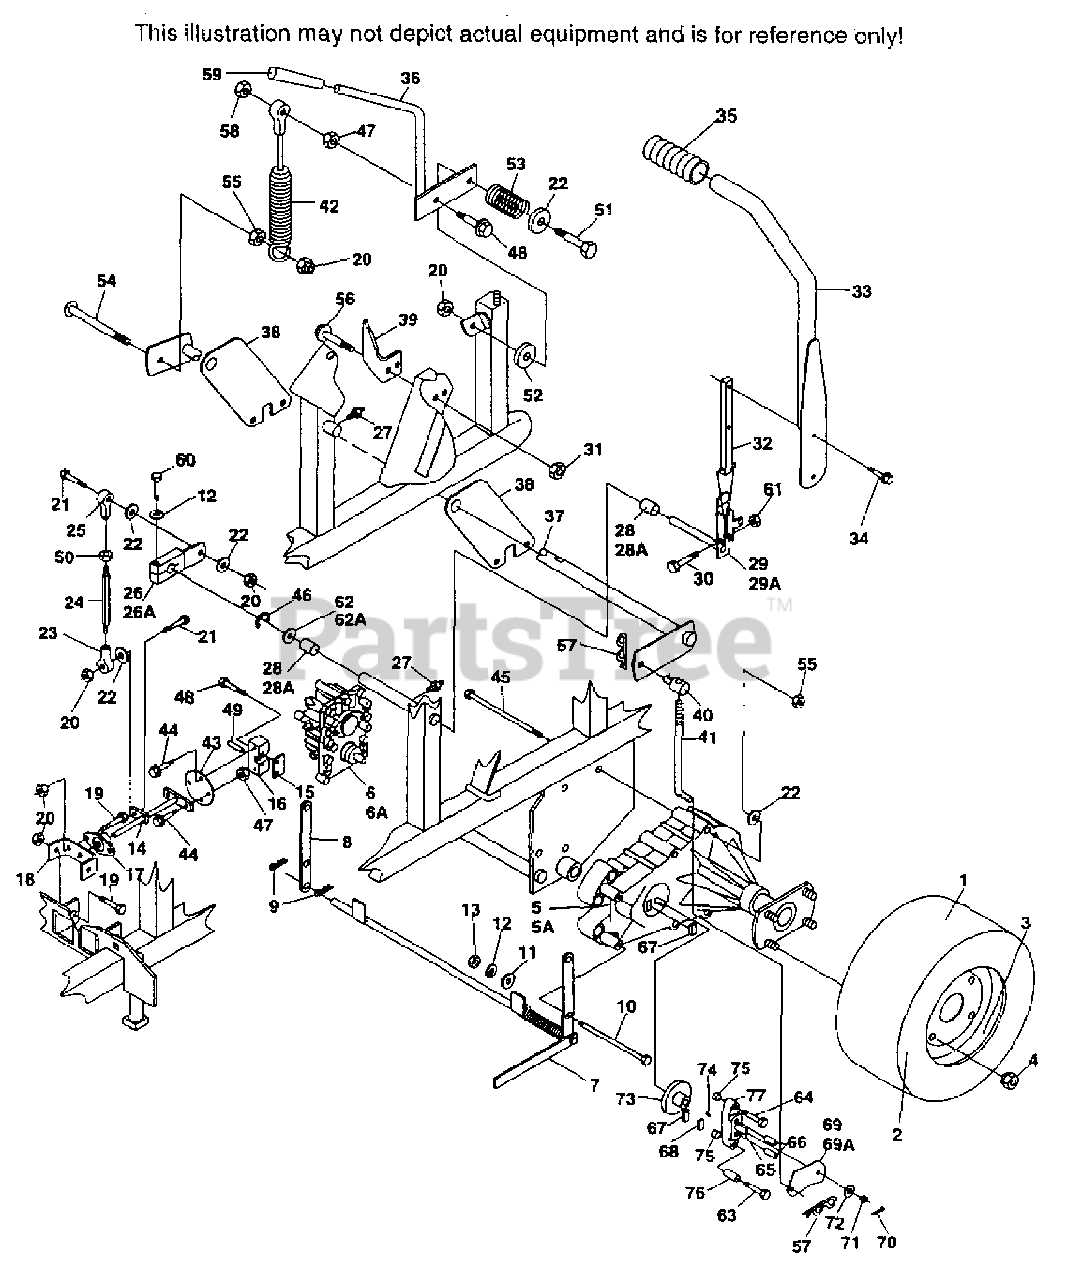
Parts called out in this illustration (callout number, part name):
1	DRIVE WHEEL ASSEMBLY
2	FUEL HOSE, 23" LONG
2	TIRE ONLY
3	RIM ONLY
4	MUFFLER CLAMP
4	LUG NUT, 1/2-20
5	AXLE, LH
5A	AXLE, RH
6	PUMP, LH
6A	PUMP, RH
7	DUMP VALVE, LEVER WELDMENT
8	MOUNTING BRACKET
9	HAIR PIN
10	HEX HEAD BOLT, 5/16-18 X 5"
14	PUMP WELDMENT SHAFT
15	CLAMP PLATE
16	BLOCK, PUMP CONTROL
17	BUSHING, SELF ALIGN
18	BEARING BRACKET
22	FLATWASHER, 3/8" SPECIAL
23	BALL JOINT, LH THREAD
24	LINK, TURNBUCKLE
25	BALL JOINT, RH THREAD
26	LEVER, PUMP TRANSFER LH
26A	LEVER, PUMP TRANSFER RH
27	GREASE FITTING
28	BUSHING, LH
28A	BUSHING, RH
29	CONTROL LEVER, LH
29A	CONTROL LEVER, RH
31	NUT, 5/16-18 SERRATED FLANGE HEX HEAD
32	BAR CONTROL LEVER
33	CONTROL HANDLE
34	CAP SCREW, 3/8"-16 X 1", SERRATED FLANGE HEX
35	GRIP, CONTROL HANDLE
37	CAM WELDMENT, PARKING BRAKE
38	PLATE, PARKING BRAKE
39	LATCH, BRAKE
40	SWIVEL JOINT
41	ROD, BRAKE
42	CABLE ASSEMBLY, PARKING BRAKE
43	PLATE, COUPLER
44	CAP SCREW, 1/4-20 X 3/4" SERRATED FLANGE HEX
46	RETAINING RING 3/4" EXTERNAL "E"
47	NUT, 1/4-20 SERRATED FLANGE HEX HEAD
48	CAP SCREW, 1/4-20 X 1-1/4" SERRATED FLANGE
49	ROLL PIN, 3/16 X 3/4"
52	FLATWASHER, 3/8 X 1-1/2" X 16 GA.
53	SPRING, BRAKE LEVER
55	NUT, 3/8-16 SERRATED FLANGE HEX HEAD
56	CAP SCREW, 5/16-18 X 3/4" SERRATED FLANGE HEX
57	HAIR PIN, 1/16" DIAMETER
59	GRIP, PARKING BRAKE
61	ELASTIC STOP NUT, 5/16-18
62	FLATWASHER, 3/4"
62A	FLATWASHER, 3/4" SPECIAL
63	BOLT, 1/4-20 X 2 1/2 GR. 5 W/PATCH
64	BOLT, 1/4-20 X 1 1/2 GR. 5 W/PATCH
65	BOLT, SQUARE HEAD
66	PINS, ACTUATING
67	BRAKE PUCK
68	BACKING PLATE
69	ACTUATING LEVER, RH
69A	ACTUATING LEVER, LH
70	COTTER PIN
71	CASTLE NUT
72	WASHER
73	DISC
74	KEY, WOODRUFF SPECIAL
75	SPACER, SMALL
76	SPACER, LARGE
77	YOKE BRAKE
